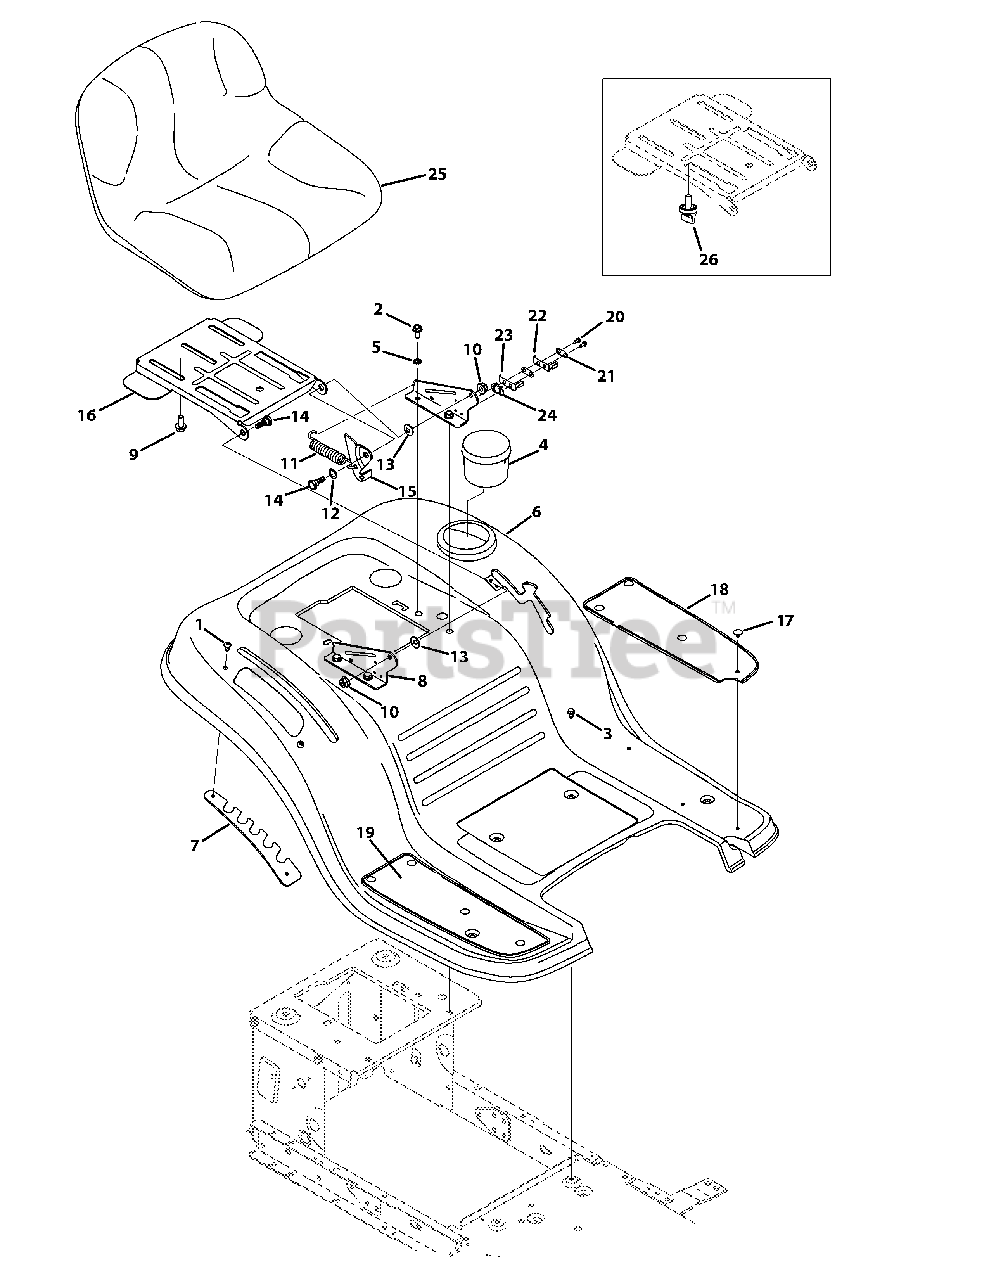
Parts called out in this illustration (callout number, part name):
1	Screw, 1/4-20 x .500
2	Screw, 5/16-18 x .750
3	Screw Pan Torx Head, 1/4-20 x .500
4	Cup Holder
5	Loack Washer, 5/16
6	Fender
7	Lift Adjuster Bracket
8	Seat Mount Bracket
9	Hex Flange, 3/8-16 x .875
10	Flangelock Nut, 5/16-18
11	Extension Spring
12	Flat Washer, .510x .750 x .033
13	Bell Washer, .340 x .872 x .060
14	Shoulder Screw, 5/16-18 x .437 x .268
15	Lift Seat Bracket
16	Pivot Seat Manual Adjust Bracket
17	Ratchet Clip, .250 x .500
18	Foot Pad, LH
19	Foot Pad, RH
20	Screw, 8-18 x .500
21	Insulator Plate
22	Outer Seat SPring
23	Inner Seat Spring
24	Insulator Boss Plate
25	Medium Back Seat
